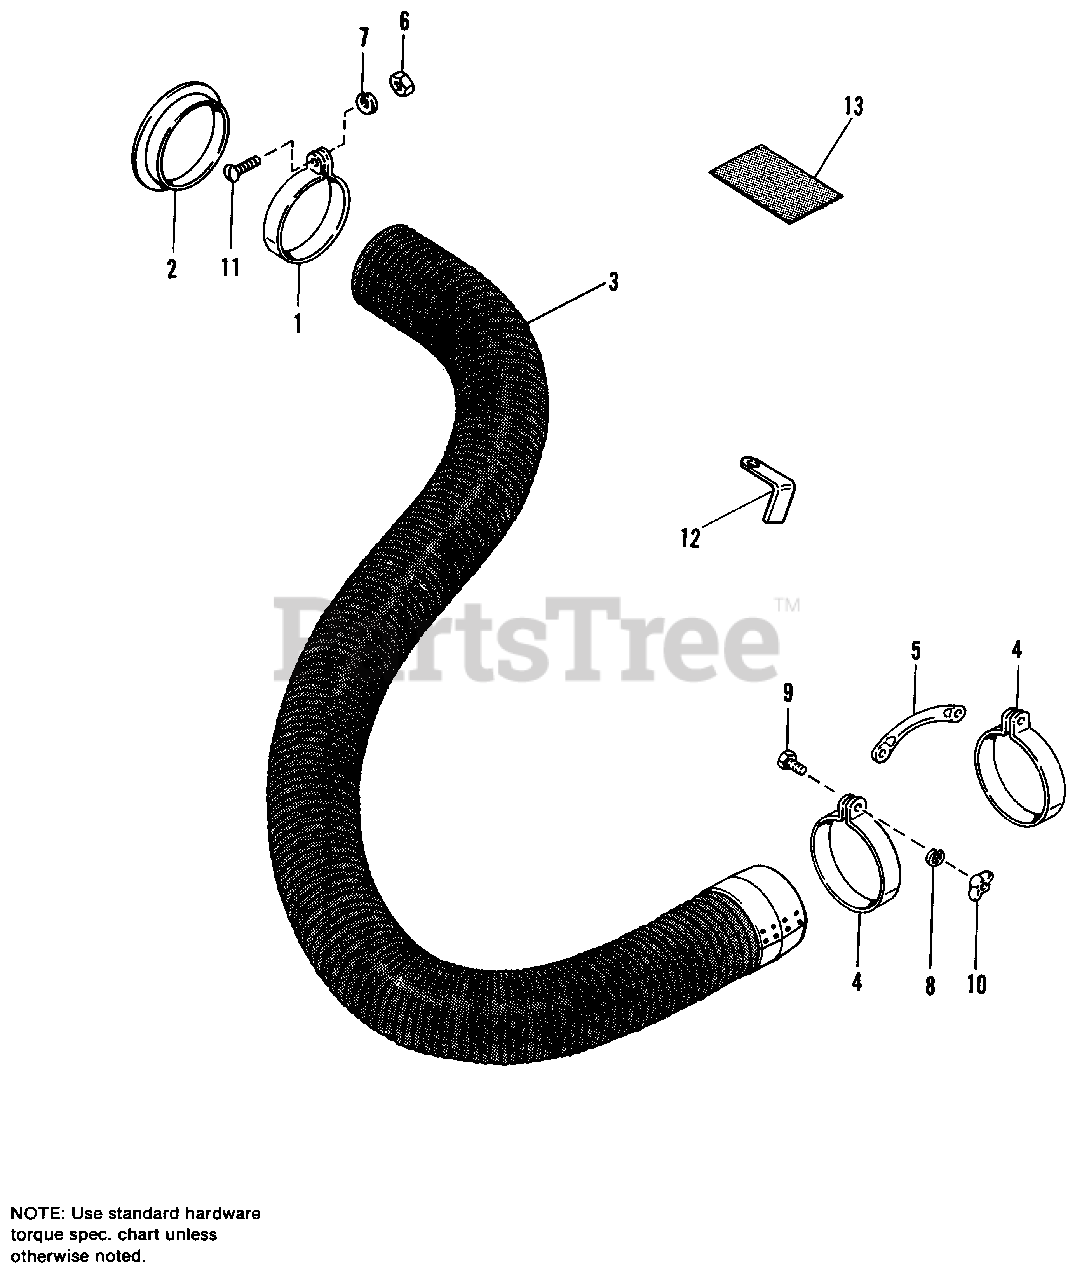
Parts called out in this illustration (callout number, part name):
1	CLAMP, Hose
2	FLANGE, Hose
3	HOSE ASSY.
4	CLAMP, Hose
5	HANDLE, Hose
6	NUT, Hex, 1/4-20
7	LOCKWASHER, Spring, 1/4
8	LOCKWASHER, Spring, 5/16
9	CAPSCREW, Hex Hd., 5/16-18 x 3/4
10	NUT, Wing, 5/16-18
11	SCREW, Rd. Hd., 1/4-20 x 3
12	STOP, Belt
13	DECAL, Warning
